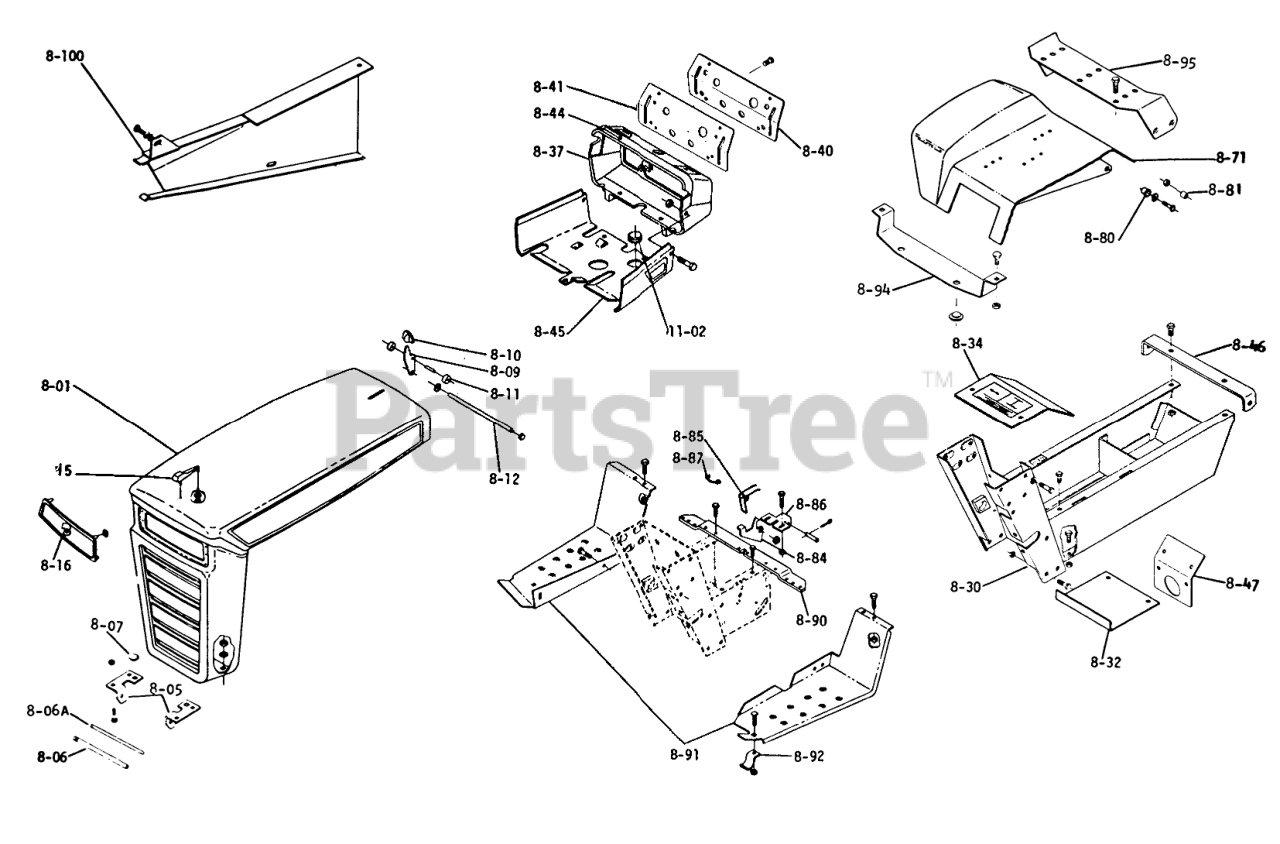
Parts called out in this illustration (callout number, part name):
8-01	Hood
8-05	GRILL PIVOT BRKT
8-05	Bracket-Grille-L.H.
8-05	Bolt Hex 5/16-18 x 3/4
8-05	Nut-Nylok
8-06	GRILL PIVOT ROD
8-06	E Ring-3/8
8-06A	ROD-HOOD STOP
8-07	GROMMET
8-09	LEVER HOOD LATCH
8-09	SPIROL PIN
8-09A	Cotter Pin
8-10	KNOB
8-11	Roller
8-12	Rod Latch
8-12	SPEED NUT
8-15	Hood Ornament
8-15	SPEED NUT
8-15	WASHER
8-16	Plate-Escutcheon
8-16	SPEED NUT
8-16	WASHER
8-30	Hoodstand Assy.
8-30	Bolt 3/8-16 x 1
8-30	Bolt 3/8-16 x 3/4
8-30	Washer
8-30	Lockwasher
8-32	Cover-Dust
8-32	Bolt 5/16-18 x
8-32	Nut-Nylok
8-34	Cover Plate
8-34	Bolt, 1/4-20 Whizlock
8-37	Housing
8-37	Bolt 1/4-20 x 5/8 Whizlock
8-37	Nut-Nylok
8-40	Panel-Dash
8-41	BACK UP PLATE
8-41	SPEED NUT
8-41	SCREW BLACK
8-44	Tape
8-45	Support-Fuel Tank
8-45	Bolt 5/16-18 x 1
8-45	SPEED CLIP
8-46	Bracket
8-46	Bolt 3/8-16 x 3/4
8-46	Nut, 3/8-16 Eslok
8-47	Instrument Backet
8-47	Bolt, 1/4-20 Whizlock
8-71	Fender
8-80	BUSHING-FLANGED
8-81	SPACER
8-81	Bolt 3/8-16 x 1
8-81	3/8-16 E.S.
8-81	Washer
8-84	Latch Fender
8-85	Spring
8-85	NYLINER BUSHING
8-85	Pin
8-85	Hairpin
8-86	BRACKET FENDER LATCH
8-86	Bolt-Hex 1/4-20
8-86	Nut-Nylok
8-87	Stop-Fender Latch
8-90	Bracket
8-90	Bolt 5/16-18 x 1
8-91	Footrest L.H.
8-91	Bolt 5/16-18 x
8-91	Nut 5/16-18
8-91	Bolt, 5/16-18 x 1/2
8-92	BRACKET
8-92	Bolt-Carriage 5/16-18
8-92	Nut 5/16-18
8-94	Fender Bracket
8-94	Bolt, 5/16-18 x 5/8 Carriage
8-94	Nut-Nylok
8-94	GROMMET
8-95	Bracket Fender Hinge
8-100	Belt Guard Assy.
8-100	Bolt Hex 7/16-4 x 3/4
8-100	Lockwasher 3/8
8-100	Washer 7/16
8-100	Bolt 3/8-16 x 3/4
8-100	Lockwasher
8-100	Washer
